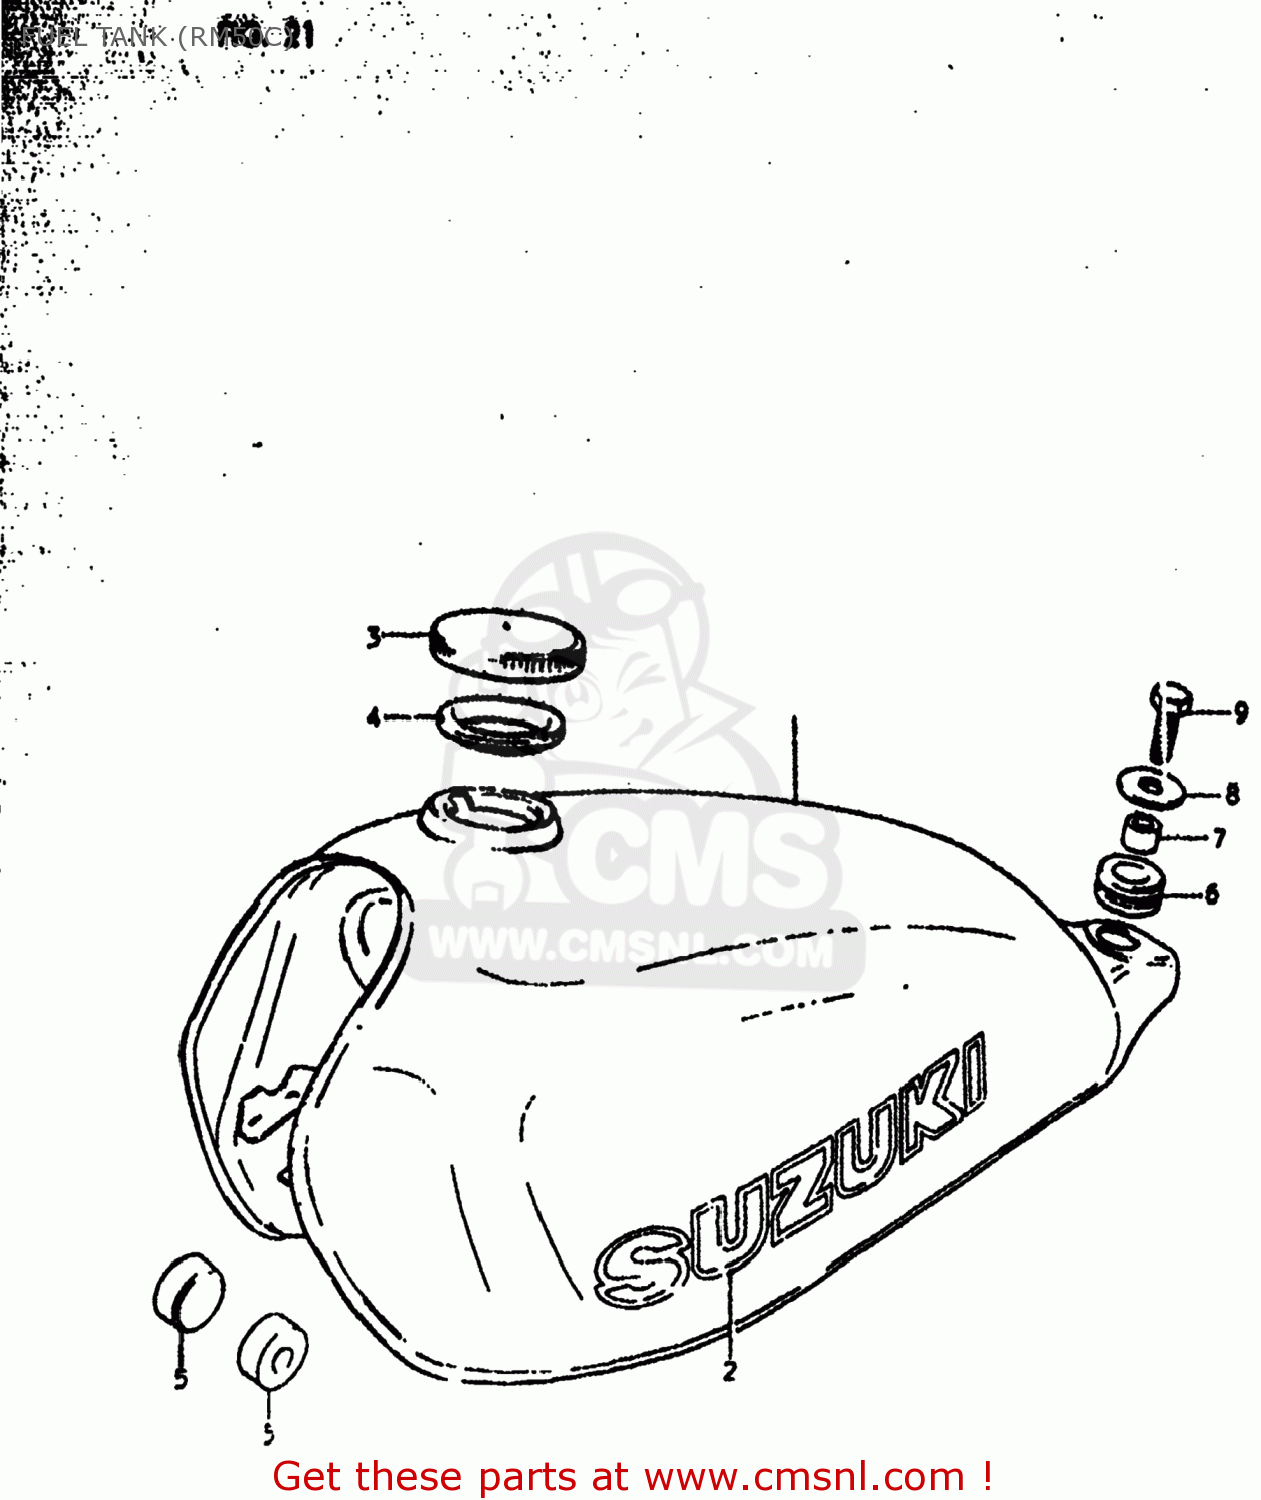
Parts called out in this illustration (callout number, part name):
1	TANK ASSEMBLY,FUEL
2	EMBLEM
3	CAP SET,FUEL TANK
4	GASKET,CAP (NAS)
5	CUSHION
6	CUSHION
7	SPACER(6.1X9X7.5)
8	WASHER (6.5X24X1.6)
9	BOLT, UPPER
